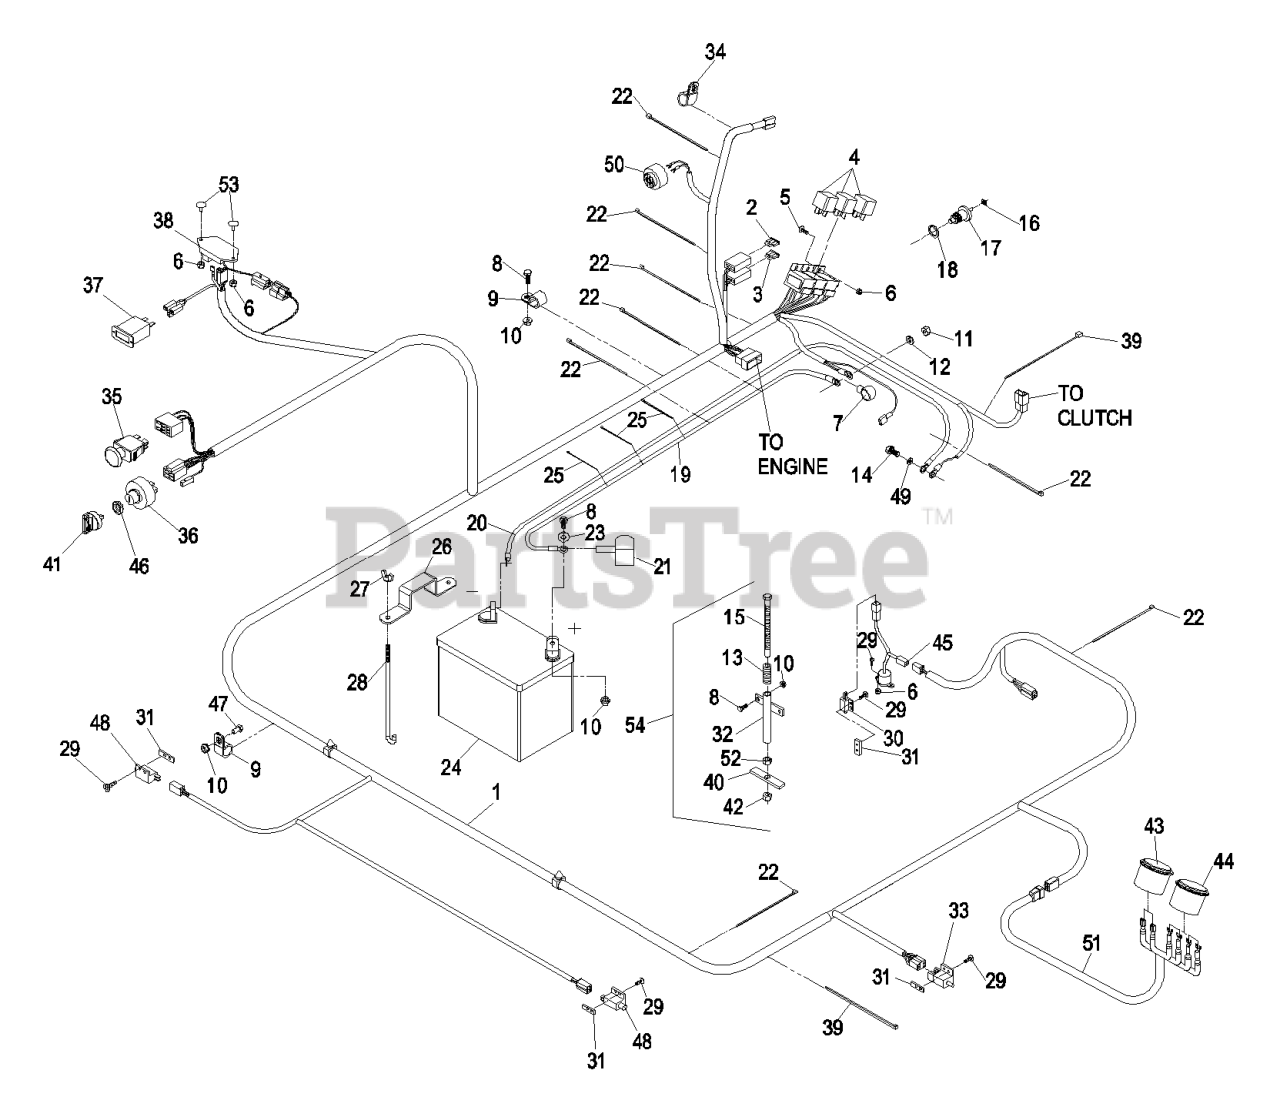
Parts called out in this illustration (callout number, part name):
1	HARNESS,WIRE LZ 27LKA
2	FUSE-BLADE TYPE, 20 AMP
3	FUSE-BLADE TYPE, 30 AMP
6	NUT-LOCK, NI
7	INSULATOR-SOLENOID
8	SCREW-HH
9	CLIP-LOOM
11	NUT-HEX
12	WASHER-PLAIN
13	SPRING-SWITCH, SEAT
14	SCREW-HH
15	SCREW-HH
17	SENDER-TEMPERATURE
18	WASHER-ALUMINUM
20	WIRE-GROUND
22	TIE-PLASTIC
23	WASHER-FLAT
25	TIE-CABLE
26	STRAP-HOLDDOWN
27	WINGNUT
28	BOLT-HOLDDOWN
29	SCREW-PPH
30	SWITCH-CLOSED, NORMALLY
31	PLATE-TAPPED
32	MOUNT-SPRING, SEAT
34	CLIP-LOOM
35	SWITCH-PTO
37	METER-HOUR
38	MODULE-DELAY, SEAT
39	TIE-PLASTIC
40	PLATE-SWITCH, SEAT
41	KEY-IGNITION
42	NUT-LOCK, NI
43	GAUGE-VOLTMETER
44	GAUGE,TEMP W/ ALERT
46	NUT-SWITCH, IGNITION
47	SCREW-HH
48	SWITCH-OPEN, NORMALLY
49	WASHER-PLAIN
50	ALARM-TONE, DUAL
51	HARNESS,GAUGE 27 LKA
52	NUT-HEX
53	BOLT-CARR
54	ASM,SEAT SWITCH ACTUATOR
